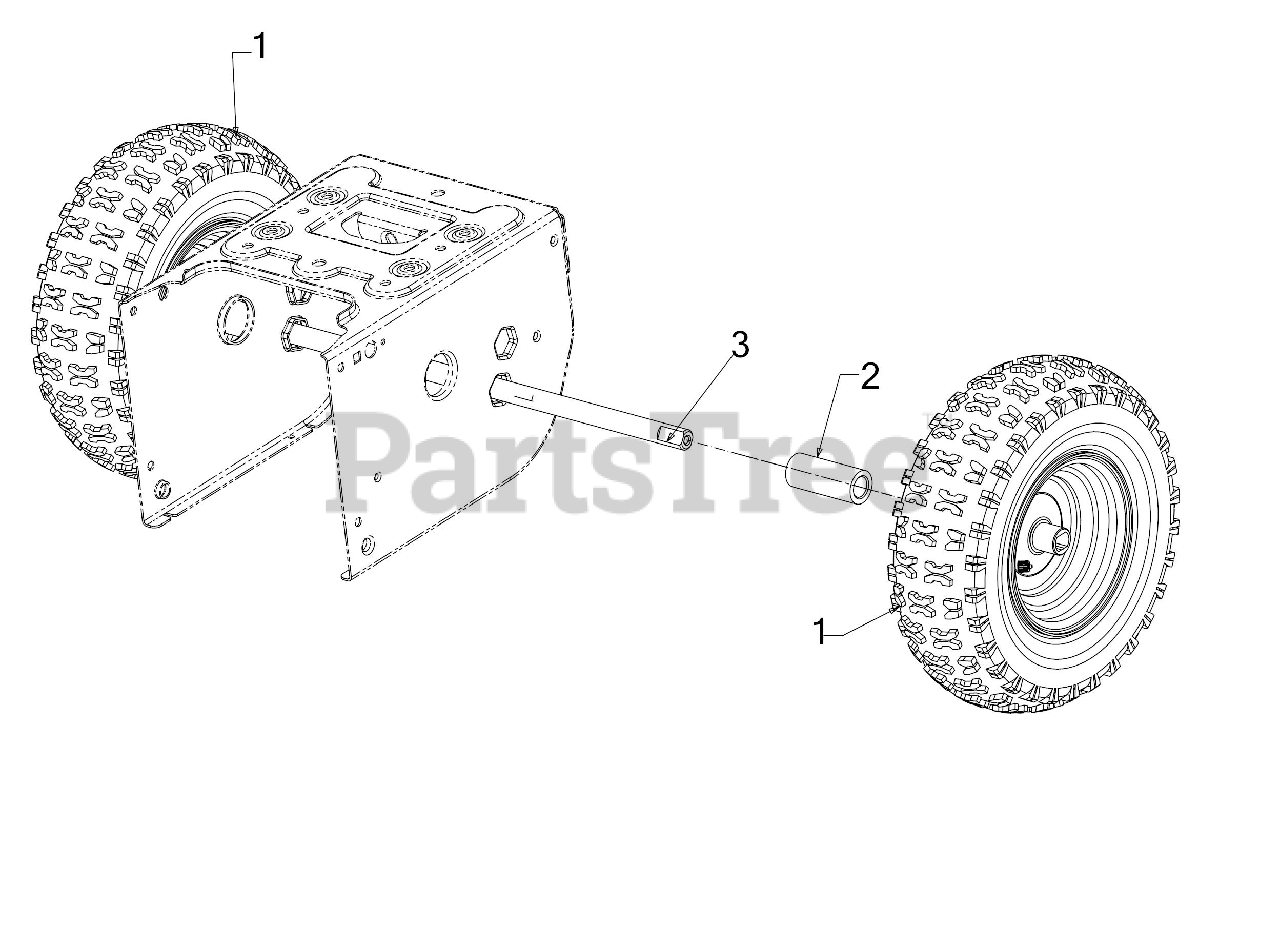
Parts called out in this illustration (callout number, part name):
1	WHEEL ASSEMBLY (13 x 4)
2	WHEEL SPACER 1.25ODX.75X3.00
3	WHEEL AXLE SHAFT .75 x 22"
